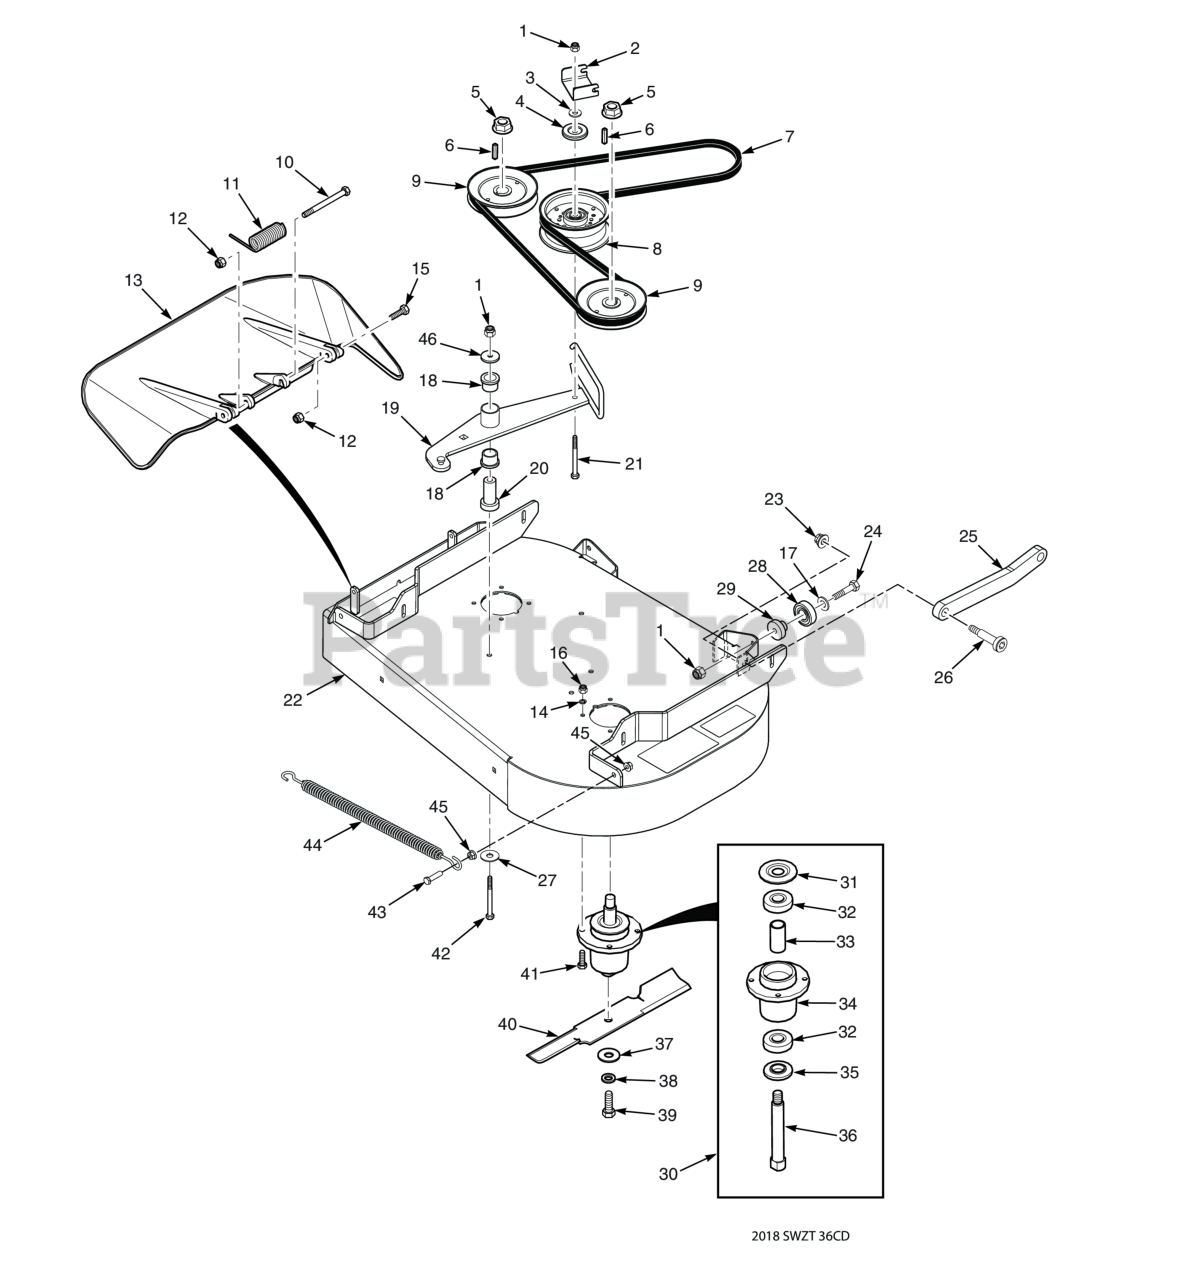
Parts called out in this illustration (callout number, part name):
1	HEX NUT, ELASTIC STOP LOCK, 3/8-16
2	Bracket, Belt Guide
3	Flatwasher, 3/8 (.391 x .938 x .105 HD) Grade 8
4	Quick Pin, 5/16" Dia.
5	Nut, 3/4-16 Spriral Lock
6	Key, 1/4 x 1/4 x 1.25" Pulley Mtg.
7	Belt, Cutter Deck
8	Pulley, Idler 5" Dia.
9	Pulley, 5.73" OD - 25mm Bore
10	Bolt, 5/16-18 x 4-3/4" Hex Head
11	Spring, Discharge Chute
12	HEX NUT, ELASTIC STOP LOCK, 5/16-18
13	Discharge Chute Assy. SFZ48
14	Lockwasher, 5/16 (.317 x .586 x .078) Helical Spring
15	Bolt, Hex Head 5/16-18 x 1-1/2" - Front
16	Lock Nut, 5/16-18 Elastic Stop Grade 8
17	Flatwasher, 3/8 (.391 x .938 x .105 HD) Grade 8
18	Bearing, Plastic
19	Idler Arm Assembly
20	Pivot, Idler
21	Capscrew, Hex Head 3/8-16 x 3.25"
22	Cutter Deck w/Decals, SMWZT-36
23	Nut, Flange Elastic Stop Nut, 3/8-16
24	Bolt, Hex Head 3/8-16 x 1-3/4" (Kohler EFI)
25	Pusharm
26	Bolt, Shoulder 1/2 x 3/8-16 x 2-3/4"
27	Flatwasher, 3/8-.406 x 2.25" x .1875
28	Bearing
29	Spacer, Bearing
30	Spindle Assembly
31	Debris Shield
32	Bearing
33	Spacer, Bearing
34	Spindle Housing Assembly
35	Protector, Bearing
36	Shaft, Spindle
37	Flatwasher, 5/8-.688 x 1-3/4 x .134 HD
38	Lockwasher, 5/8" Spring
39	Bolt, Hex Head 5/8-11 x 1-1/2"
40	Cutter Blade, 18" (52V)
41	Bolt, Hex Head 5/16-18 x 1-1/2" Grade 8
42	Capscrew, Hex Head 3/8-16 x 3-3/4"
43	Bolt, Hex Head 3/8-16 x 1-1/2" Grade 8 Black
44	Spring, Cutter Deck Idler
45	NUT, 3/8-16 SERRATED FLANGE HEX HEAD
46	Flatwasher, 3/8-.406 x 1-1-1/2 x 7 Gauge
